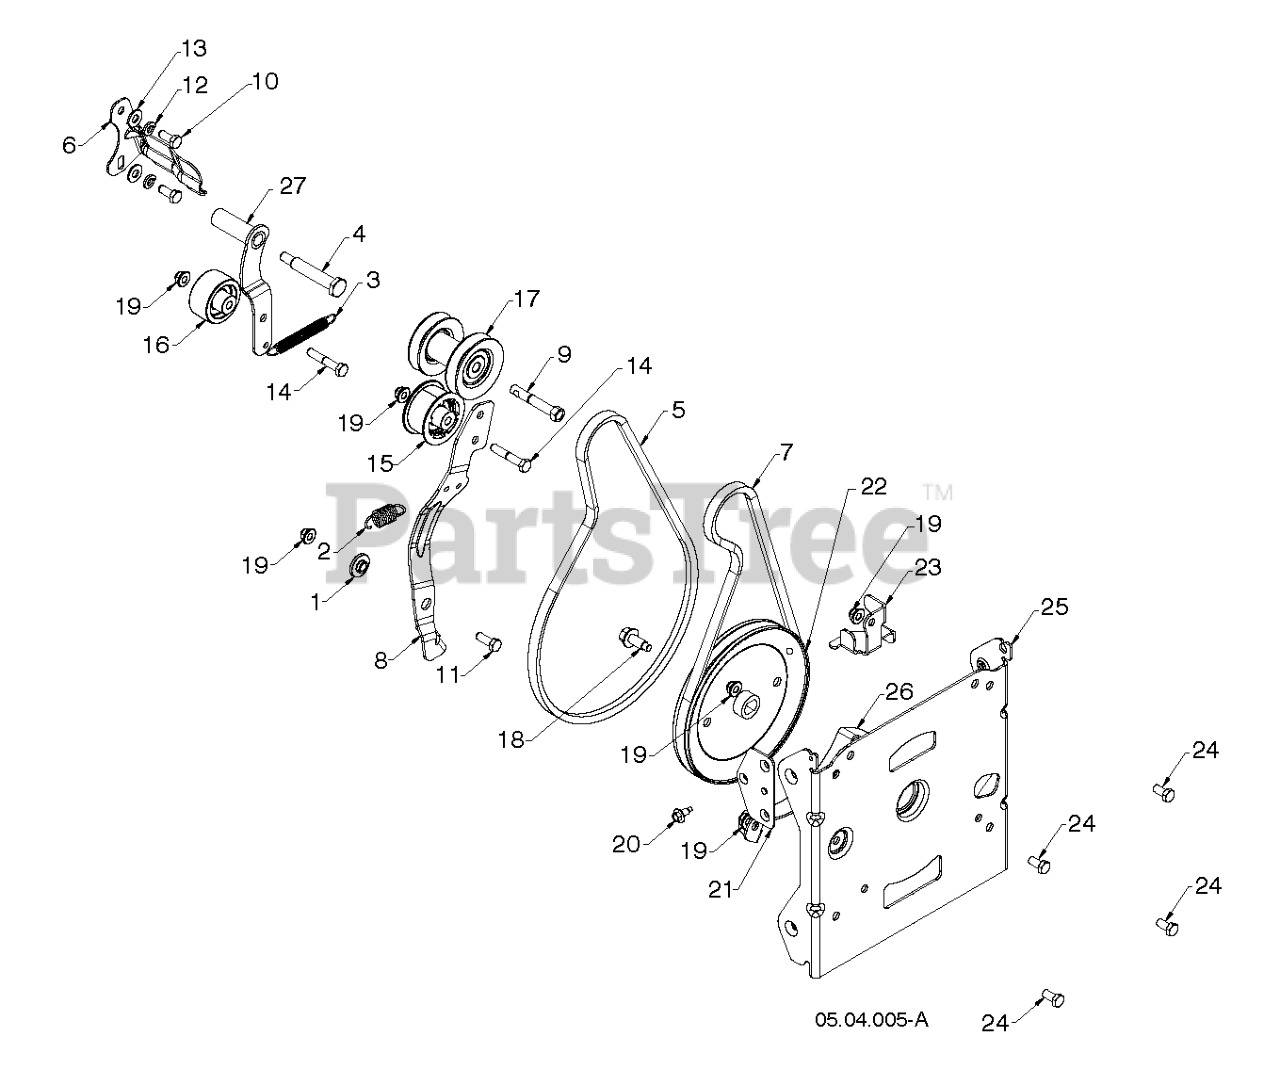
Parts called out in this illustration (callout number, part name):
1	BUSHING.BRAKE.ARM
2	SPRING RETURN, IDLER ARM, IMPE
3	SPRING RETURN IDLER ARM
4	BOLT 5/16-24X2.25 HEX HEAD SHO
5	BELT.DRIVE.SNOW.DUAL
6	BELT KEEPER BRACKET
7	LOW CRANK IMPELLER BELT
8	ARM.IDLER.AUTO-PH.676
9	BOLT.ENGINE.PULLEY
10	SCREW 5/16-24 X .75 GR5
11	Hex, Bolt 5/16 x 18 UNC x 7/8 (AYP part number)
12	Washer Lock Hvy Hlcl 1/4 (Order from Engine Manufacturer) (AYP part number)
13	Washer 11/32 x 3/4 x 16 Gauge (AYP part number)
14	Bolt, Hex 5/16-18 x 1-3/4 (AYP part number)
15	PULLEY,IDLER,2.00 W SPA
16	PULLEY.IDLER.FLANG.2.O/SPACER
17	PULLEY.ASM.IMPELLER/DRIVE
18	SCREW FLANGE HEAD CAP WITH DOG
19	NUTNYLOK.FLRANGE.5/16-18
20	HEX.WASHER.HEAD 1/4-20 X .65
21	BRACKET NUT BLACK ZINC PLATE
22	PULLEY IMPELLER DD 4L
23	GUIDE.LOWER.AUGER.BELT.479
24	BOLT, HEX HEAD 5/16-18
25	BRACKET.AUG.HOUSING.INTER.BLAC
26	BRACKET.BELT.KEEPER.LOWER.BLAC
27	ARM IDLER DRIVE WELDMENT_HOT
